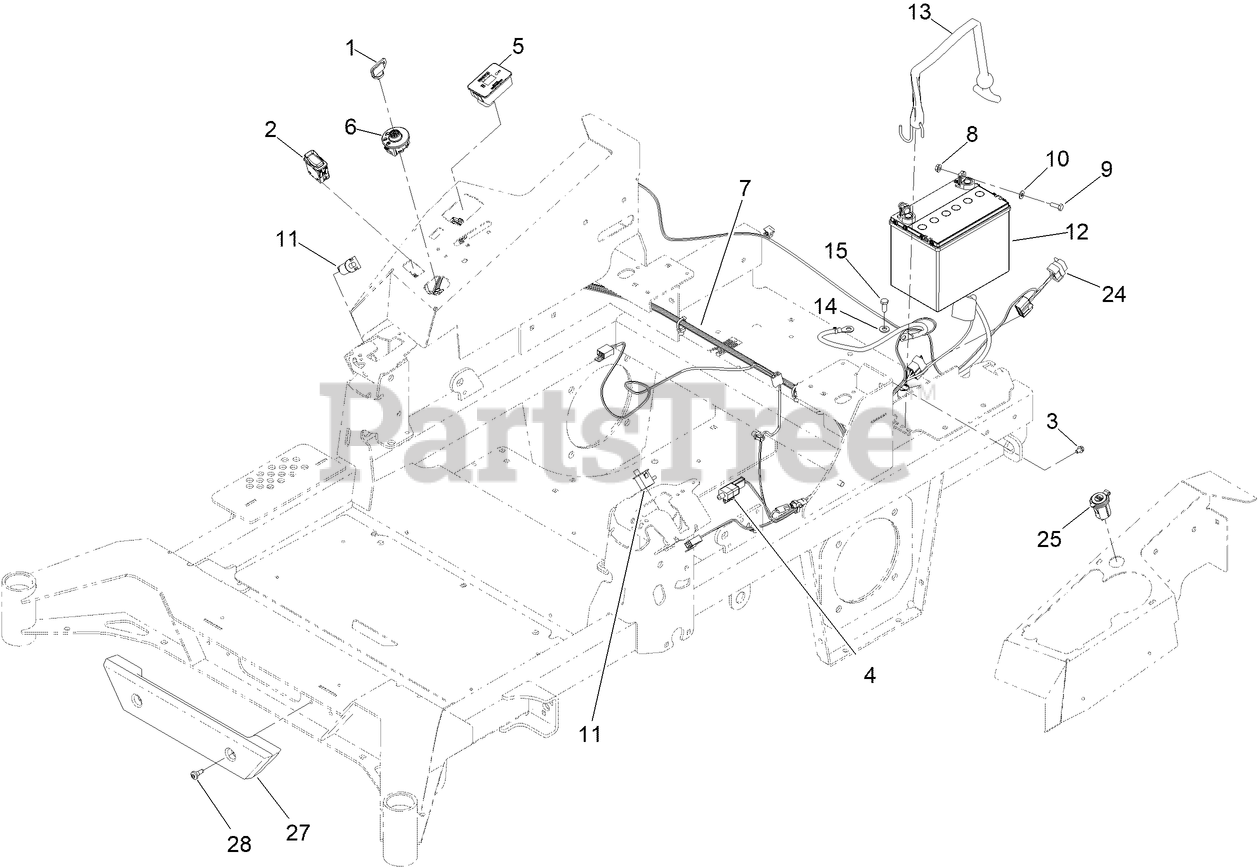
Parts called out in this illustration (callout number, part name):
1	KEYS-IGNITION (SPARE PAIR)
1	KEY-IGNITION
2	SWITCH-ROCKER, ON-NONE-ON
3	SCREW-HWH
4	SWITCH
5	MODULE ASM
6	SWITCH-IGNITION
7	HARNESS-WIRE
8	NUT-HF
9	SCREW-HH
10	WASHER-FLAT
11	SWITCH-BAIL
12	BATTERY-DRY
13	STRAP, BUNGEE
14	WASHER-PLAIN
15	SCREW-HH
24	HARNESS-WIRE, ADAPTER
25	PORT-POWER, USB
27	BUMPER-FRONT
28	SCREW-SHOULDER
